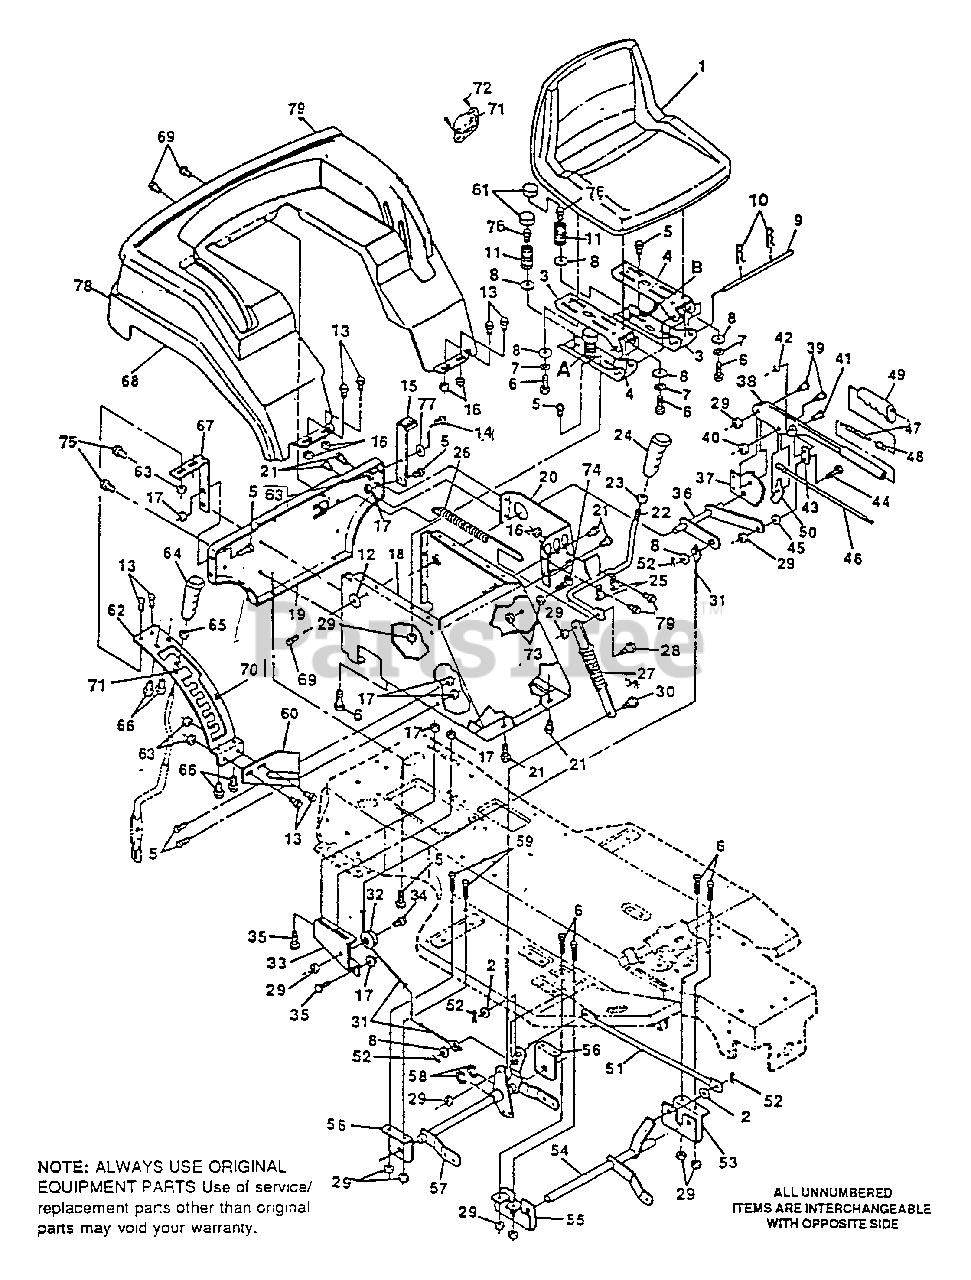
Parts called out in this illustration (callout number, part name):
2	Washer, Flat 13/32 In.
3	Channel, Seat L. H.
4	Channel, Seat R. H.
5	Screw, Hx Hd, Wd Fl 5/16-18 x 3/4 In.
6	Screw, Hx Hd, 5/16-18 x 3/4 In.
7	Washer, Split Lock, 5/16 In.
8	Washer, Flat, 11/32 In.
9	Rod, Seat Support
10	Hair Pin, .073 Dia. x 1.13 In.
11	Seat Spring
12	Washer, Flat, 9/32 In.
13	Screw, Hx Hd, 1/4-20 x 5/8 In.
14	Screw, 1/4-20 x .75
15	Fender Support, L.H.
16	Nut, Lock 1/4-20 Thd.
17	Nut, Hx, Wd Fl, Lk 5/16-18 Thd
18	Seat Support
19	Support, Fender & Seat
20	Bracket, Support Engage
21	Screw, Hx Wshr Hd Tap, 5/16-18 x 1/2 In.
22	Assembly, Engagement Rod
23	Nut, Hx Ctrlk, 1/2-13 Thd.
24	Handle, Lift
26	Spring, Tension
27	Assembly, Spring Cartridge
28	Shoulder Bolt, 7/16 In.
29	Nut, Hx Ctrlk, 5/16-18 Thd.
30	Shoulder Bolt, 5/16-18 Thd.
31	Cable, Deck Lift
33	Assembly, Pulley Bracket
34	Shoulder Bolt, 5/16-18 Thd.
35	Bolt, Carriage, 5/16-18 x 5/8 In.
36	Assembly, Upper Shaft
37	Quadrant
38	Lift Lever
39	Shoulder Bolt, 5/16-18 Thd.
40	Nut, Hx Wd Fl Lk 5/16-18 Thd.
41	Clevis Pin
44	Shoulder Bolt, 5/16-18 Thd.
46	Actuator Rod
47	Spring, Height Adjust
48	Knob, Height Adjust
49	Handle, Lift
50	Pawl, Height Adjust
52	Cotter Pin
53	Bracket, L.H. Front Hanger
54	Assembly, Front Lift Shaft
55	Bracket, R.H. Front Hanger
56	Bracket, Hanger
57	Assembly, Rear Lift Shaft
59	Screw, Hx Hd, 5/16-18 x 5/8 In.
60	Support, Shift Plate
61	Cover, Seat Spring
62	Quadrant
63	Nut, Hx, Wd Fl Lk, 1/4-20 Thd.
65	Nut, Hx 3/8-16 Thd.
66	Screw, Hx Hd, Tap, 10 x 1/2 In.
67	Fender Support, R.H.
69	Screw, Hx, Wshr Hd, Tap 1/4-20 x 5/8 In.
70	Screw, 1/4-20 x 1/2 In.
71	Seal Switch
72	Screw, 1/4-20 x .38
73	Nut, Hex Keps, 3/8-16 Thd.
74	Screw, Hex, 3/8-16 x 2-1/4 In.
75	Screw, Tap, 5/16-18 x 7/8 In.
76	Screw, 5/16-18 x .63, Taptite
77	Washer, Flat
78	Decal, Shift-N-Go
79	Decal, Rear Fender
